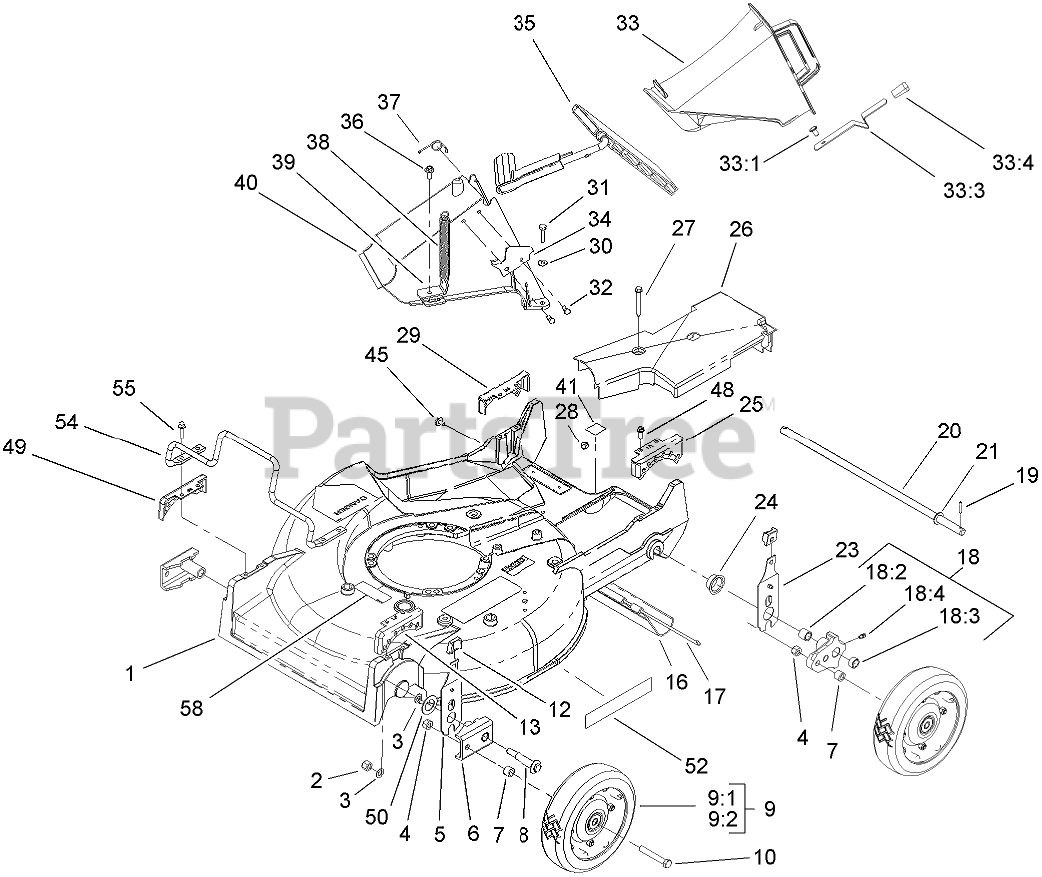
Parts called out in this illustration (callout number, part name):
1	HOUSING ASM
2	NUT-LOCK
3	WASHER
4	NUT-LOCK, CONE
5	FRONT SPRING ARM ASM
6	ARM-PIVOT, FRONT
7	SPACER-WHEEL
8	BOLT-WHEEL
9	Wheel and Tire ASM
9:2	Wheel ASM
10	SCREW-HH
12	KNOB-ARM
13	QUADRANT-FRONT, LH
16	SHIELD-TRAILING
17	ROD-SHIELD
18	PIVOT ARM ASM
18:2	BUSHING
18:3	BUSHING
18:4	FITTING-GREASE
19	PIN-SPIROL
20	SHAFT-AXLE, REAR
21	WASHER-PLAIN
23	REAR SPRING ARM ASM
24	CAP-END
25	QUADRANT-REAR, LH
26	COVER-BELT
27	SCREW-HHFTF
28	NUT-LOCK, NI
29	QUADRANT-REAR, RH
30	WASHER-FLAT
31	SCREW-HH
32	SCREW-PLASTITE
33	DISCHARGE PLUG ASM
33:1	RIVET-HEAD, FLAT
33:3	LATCH-PLUG, DISCHARGE
33:4	GRIP-LATCH
34	LATCH-PLATE
35	DISCHARGE DOOR ASM
36	SCREW-HWH
37	RETAINER-DOOR
38	SPRING-DOOR
39	BRACKET-SPRING
40	TUNNEL-DISCHARGE
41	LABEL-GREASE, HP
45	SCREW AND WASHER ASM
48	SCREW-HWHTF
49	QUADRANT-FRONT, RH
50	WASHER-THRUST
54	GUARD-ENGINE
55	SCREW-HWHTF
58	DECAL-BLADE
